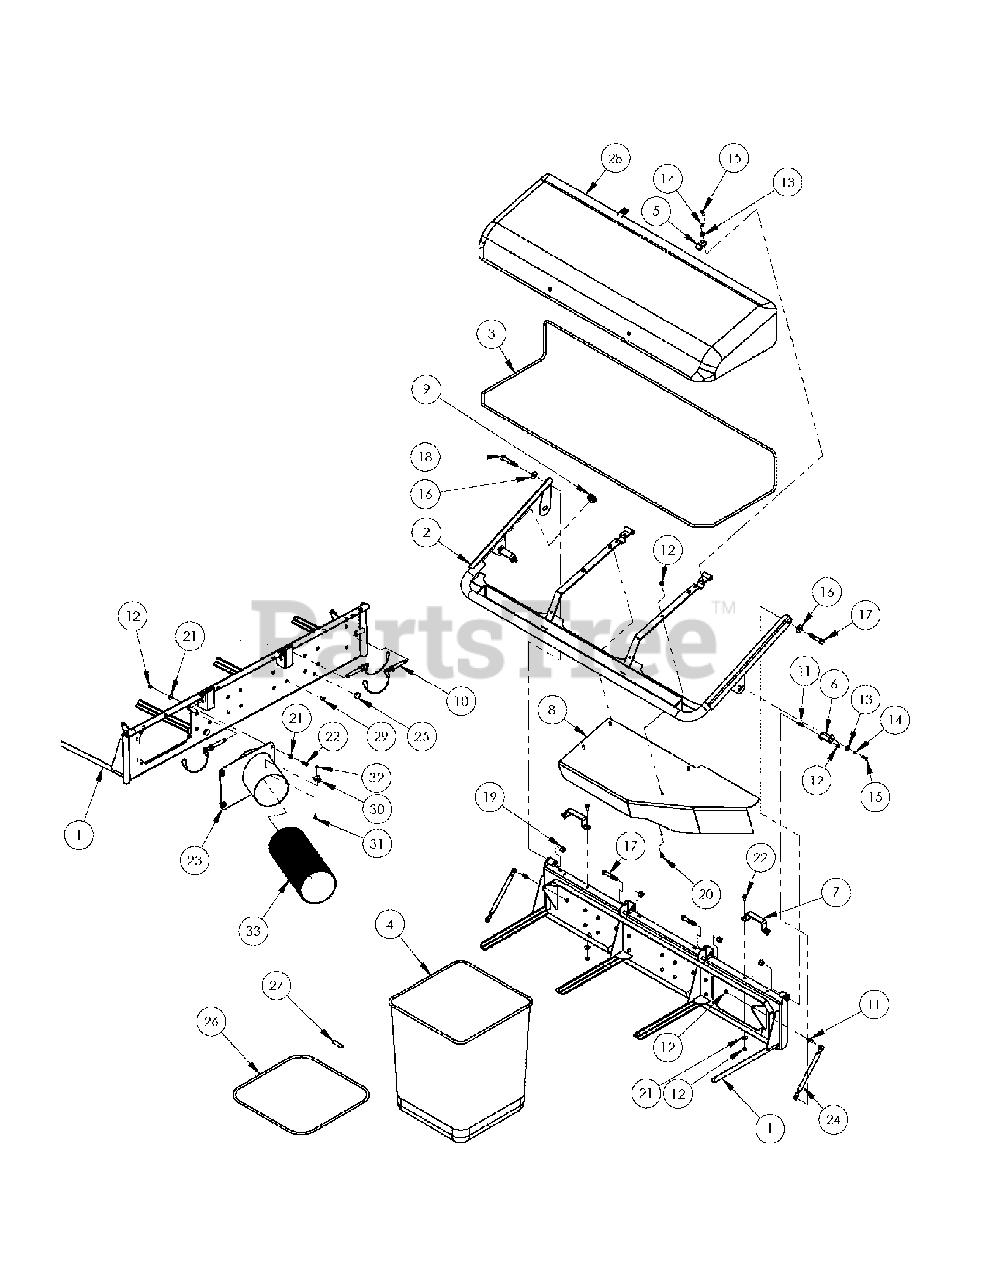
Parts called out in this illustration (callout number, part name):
1	3 BAG CATCHER BAG SUPPORT MOUNT
2	3-BAG CAP SUPPORT
3	AIR DOME FRAME, 3 BAG-3/8" ROD ONE
4	COMMERICAL CATCHER BAG
5	BRACKET-SINGLE HOLE MOUNT
6	BRACKET-GAS CYLINDER MOUNT
8	3 -BAG DEFLECTOR
9	PLUG, BLACK PLASTIC-1 1/2" TUBE
10	DETENT PIN W/ LANYARD-1/2" X 2 1/2" LONG
11	BALL JOINT
12	HEX NUT, NYLON INSERT-5/16"-18
13	FLAT WASHER-1/4"
14	LOCK WASHER-1/4"
15	CAP SCREW-1/4-20 X3/4" LONG
16	FLAT WASHER-1/2"
17	CAP SCREW-1/2"-13 X 2 1/2" LONG
18	CAP SCREW-1/2"-13 X 3" LONG
19	HEX NUT, NYLON INSERT-1/2"-13
20	PAN HEAD SCREW-5/16"-18 X 3/4" LONG
21	FLAT WASHER-5/16" LONG
22	CAP SCREW-5/16"-18 X 3/4" LONG
23	6" INLET TUBE ASSEMBLY
24	GAS CYLINDER
25	RUBBER BUMPER
26	COMMERCIAL GRASS BAG FRAME
27	PLASTIC FRAME CONNECTOR
28	AIR DOME CAP WITH "J" STRIP-PLAIN
29	PLUG, BLACK PLASTIC-7/16" HOLE
30	SPRING CLIP
31	MACHINE SCREW-#10-24 X 1/2" LONG
32	HEX NUT, NYLON INSERT-#10-24
33	3 BAG HOSE
